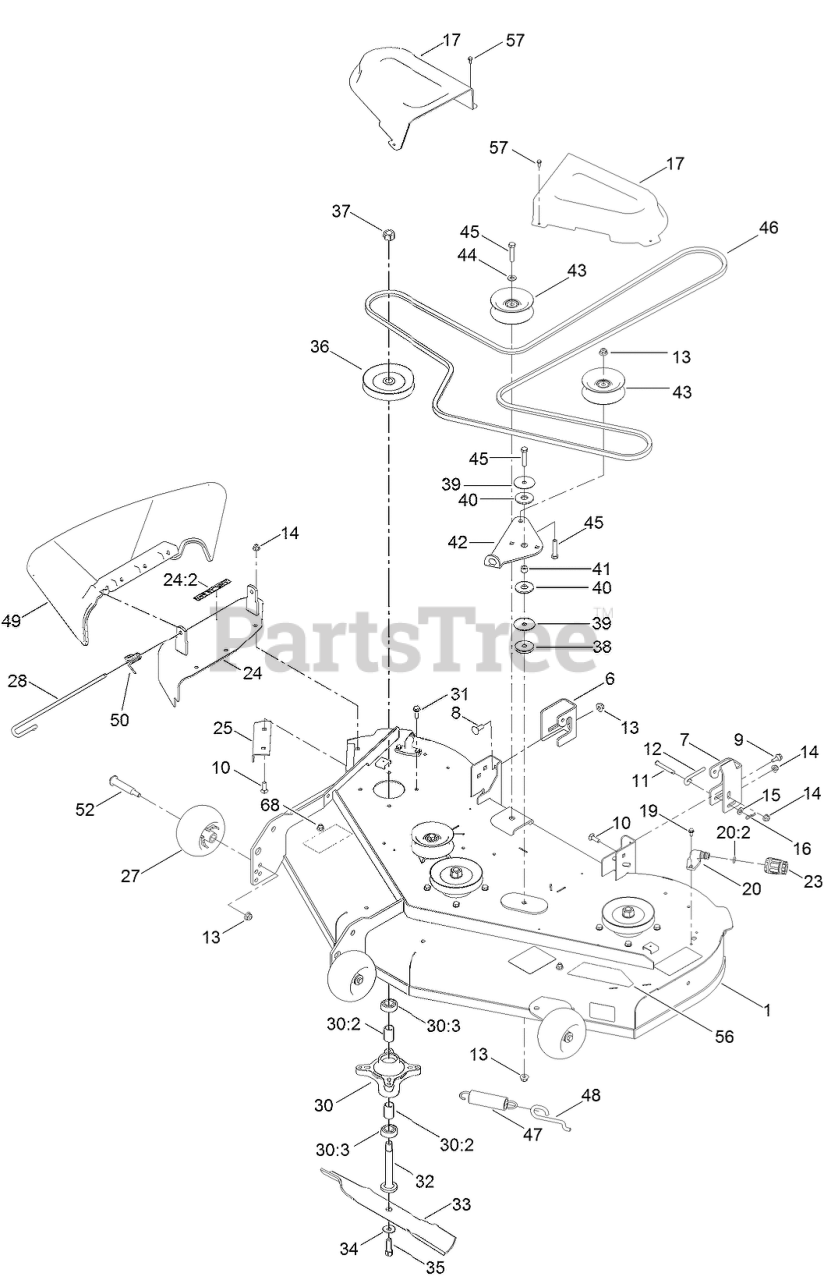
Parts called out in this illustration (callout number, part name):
1	DECK AND DECAL ASM
6	BRACKET-HANGER, RH
7	BRACKET-HANGER, LH
8	BOLT-CARR
9	SCREW-SHOULDER, HHF
10	SCREW-CARR
11	PIN-CLEVIS
12	ROD-LEVEL, DECK
13	NUT-HF, NI
14	NUT-HF, NI
15	WASHER-PLAIN
16	PIN-COTTER
17	COVER-BELT
19	SCREW-HWH
20	FITTING-WASHOUT
20:2	O-RING
23	CONNECTOR-HOSE
24	COVER ASM W/DECAL
24:2	DECAL-DANGER
25	BAFFLE-CUTOFF
27	ROLLER-SCALP, ANTI
28	PIN-CHUTE
30	SPINDLE ASM
30:2	SPACER
30:3	BEARING-BALL
31	SCREW-TAPTITE
32	SHAFT-SPINDLE
33	BLADE-HI LIFT
34	WASHER-BELLEVILLE
35	SCREW-HH
36	PULLEY
37	NUT-HEX
38	WASHER-PLAIN
39	WASHER
40	WASHER-FRICTION, COMPOSITE
41	SPACER
42	ARM-IDLER
43	PULLEY-IDLER, FLAT
44	WASHER-FLAT
45	SCREW-HH
46	V-BELT
47	SPRING-EXTENSION
48	HOOK-RETURN, SPRING
49	DEFLECTOR-DISCHARGE
50	SPRING-TORSION
52	BOLT-SHOULDER
56	DECAL-DECK
57	SCREW-TAPTITE
68	SCREW-HH
